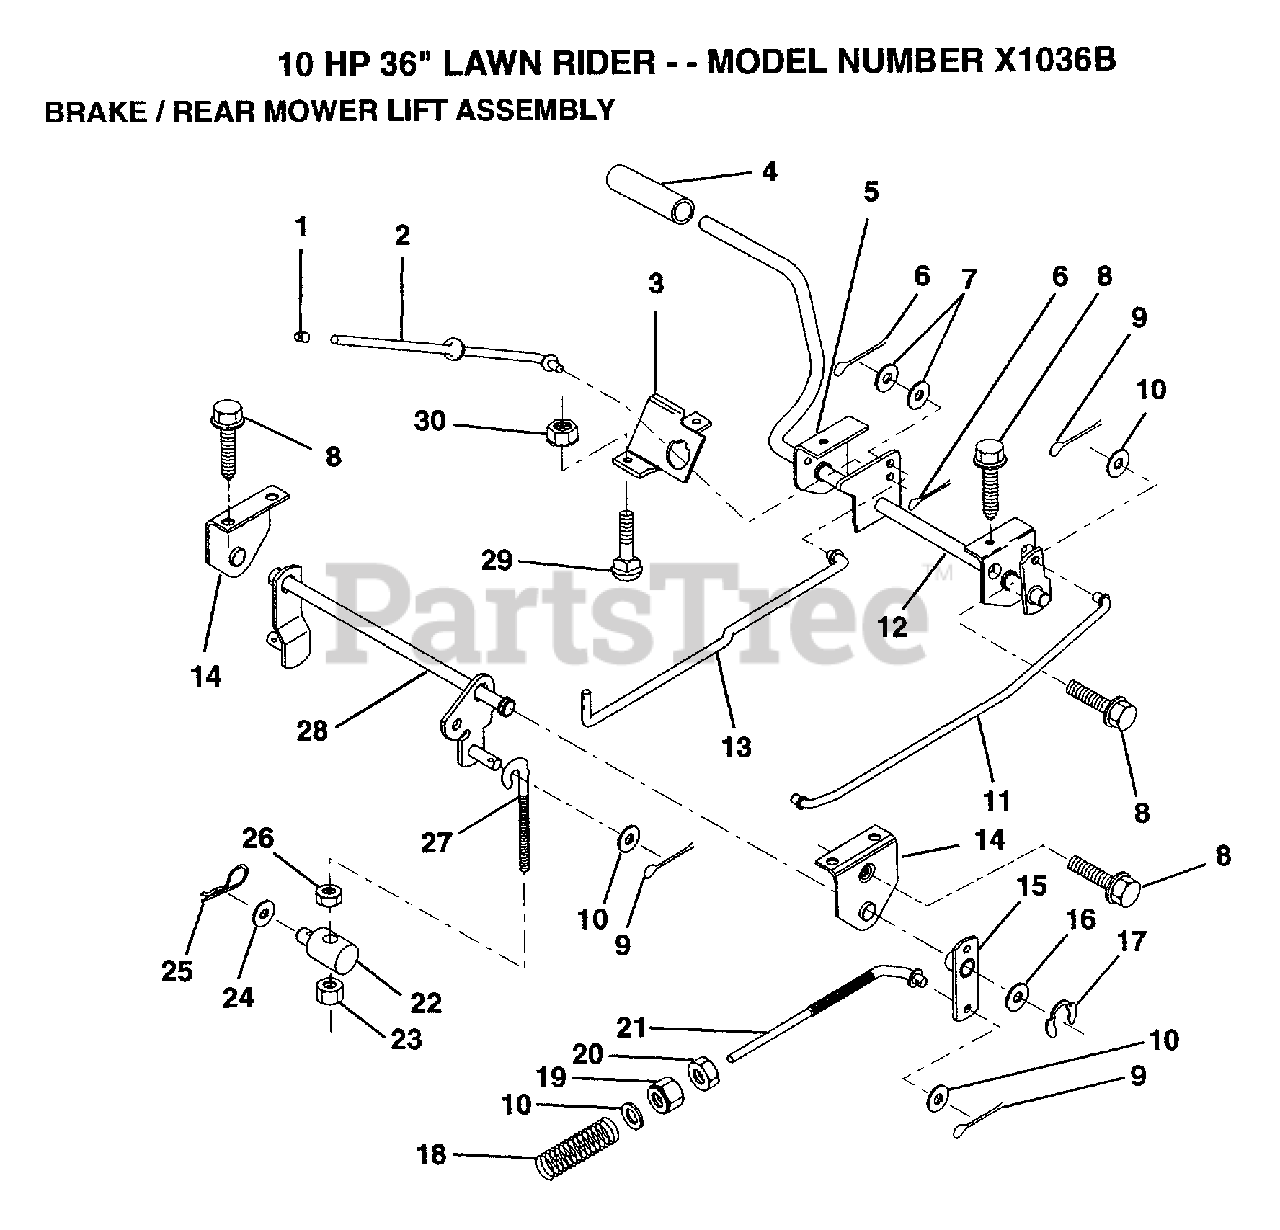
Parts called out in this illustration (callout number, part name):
2	"ROD,PARK BRAKE"
3	"BRKT,PARK BRAKE"
4	PEDAL COVER T
5	"BRKT,CLU PEDAL LH"
7	WASHER
8	SCREW LT
9	COTTER PIN
10	WASHER
13	"ROD,CLUTCH"
14	"BRKT,LIFT SHAFT"
15	PVT BRAKE ARM ASM
16	WASHER T
17	KLIP RING
18	SPRING ROD LT
19	NUT
20	NUT
24	WASHER
25	SPRING.RETAINER
26	LOCKNUT
27	"LINK, MOWER REAR"
